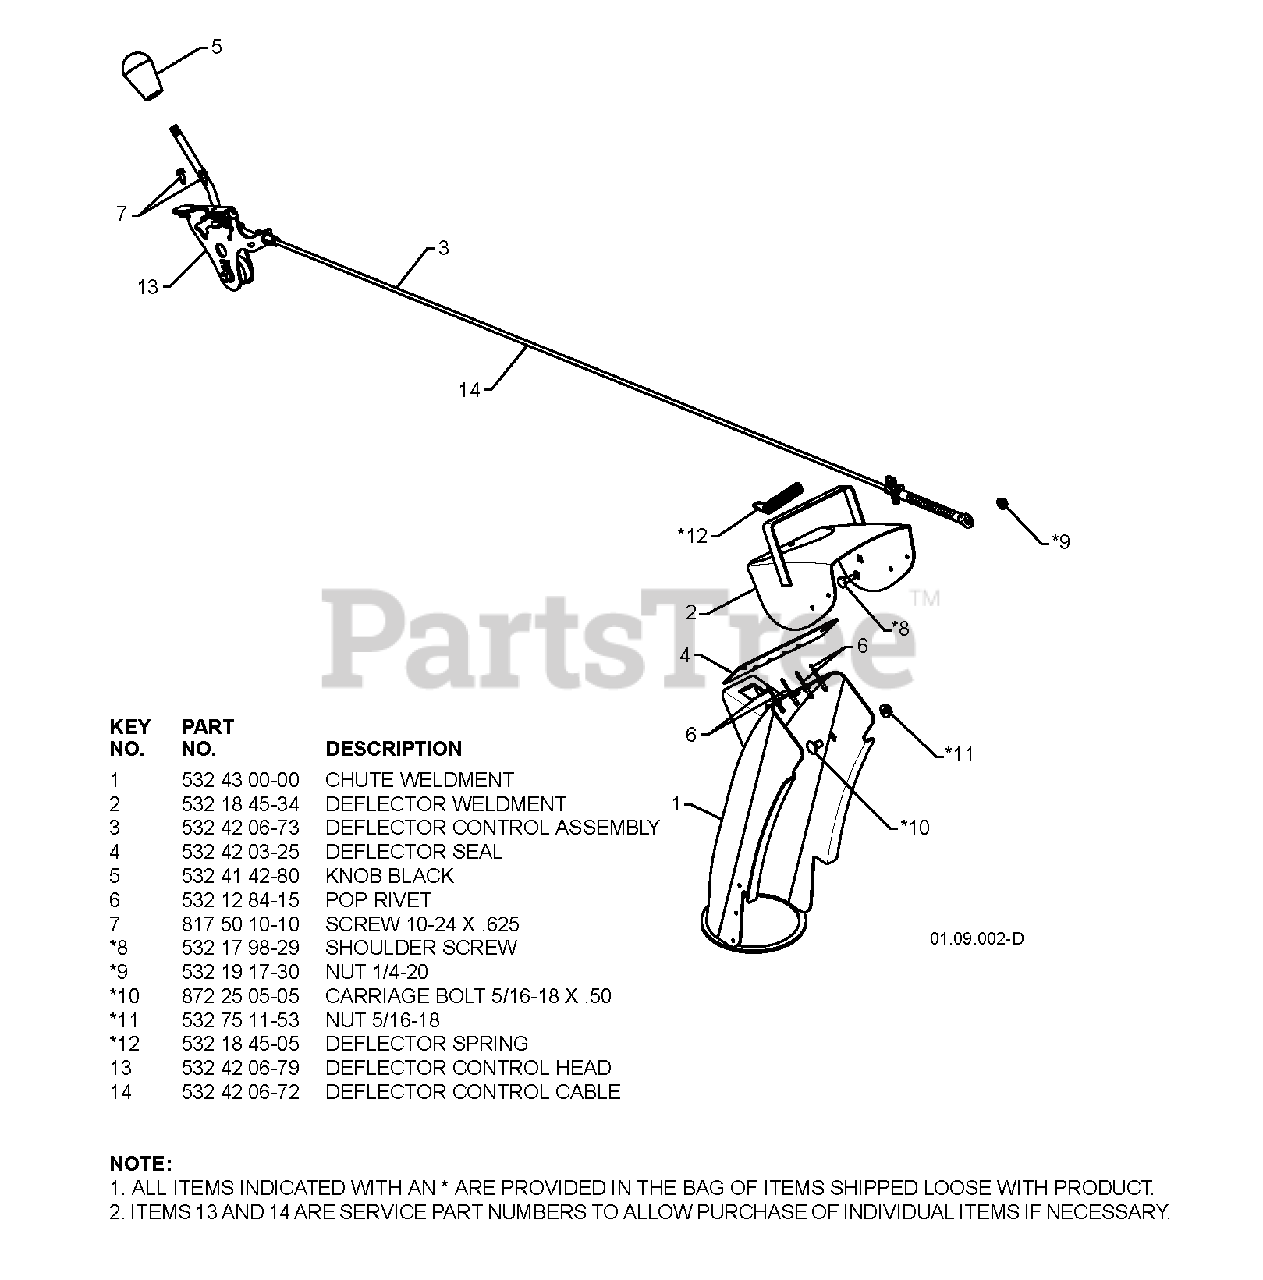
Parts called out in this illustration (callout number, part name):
3	CONTROL.ASM.DEFLECTOR
4	SEAL.DEFLECTOR
5	KNOB LEVER, BLACK
6	RIVET BLIND
7	SCREW #10-24 X 5/8
8	BOLT, SHOULDER
9	NUT.HEX.FLANGE.1/4
10	BOLT
11	NUT, LOCK 5/16-18
13	CHUTE.DEFLECTOR.HEAD.SERVICE.
14	SERVICE.CHUTE.DEF.CBL.BLK
